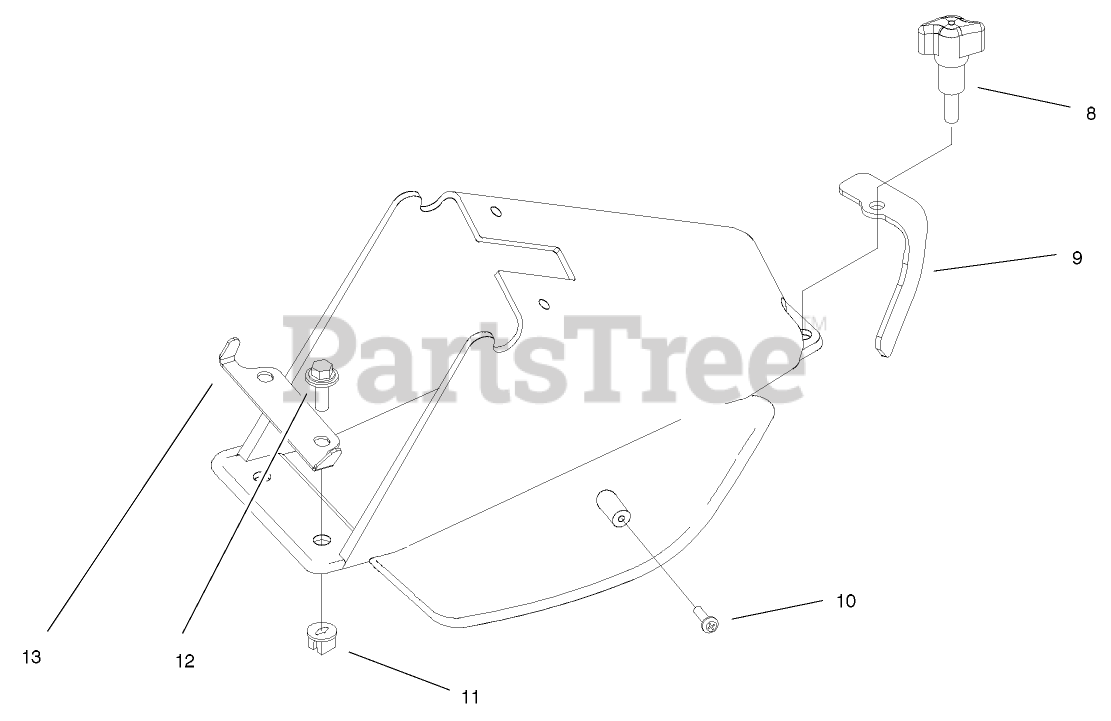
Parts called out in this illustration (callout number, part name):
9	CLAMP-DOOR
10	SCREW-PPH
12	SCREW-HWH
